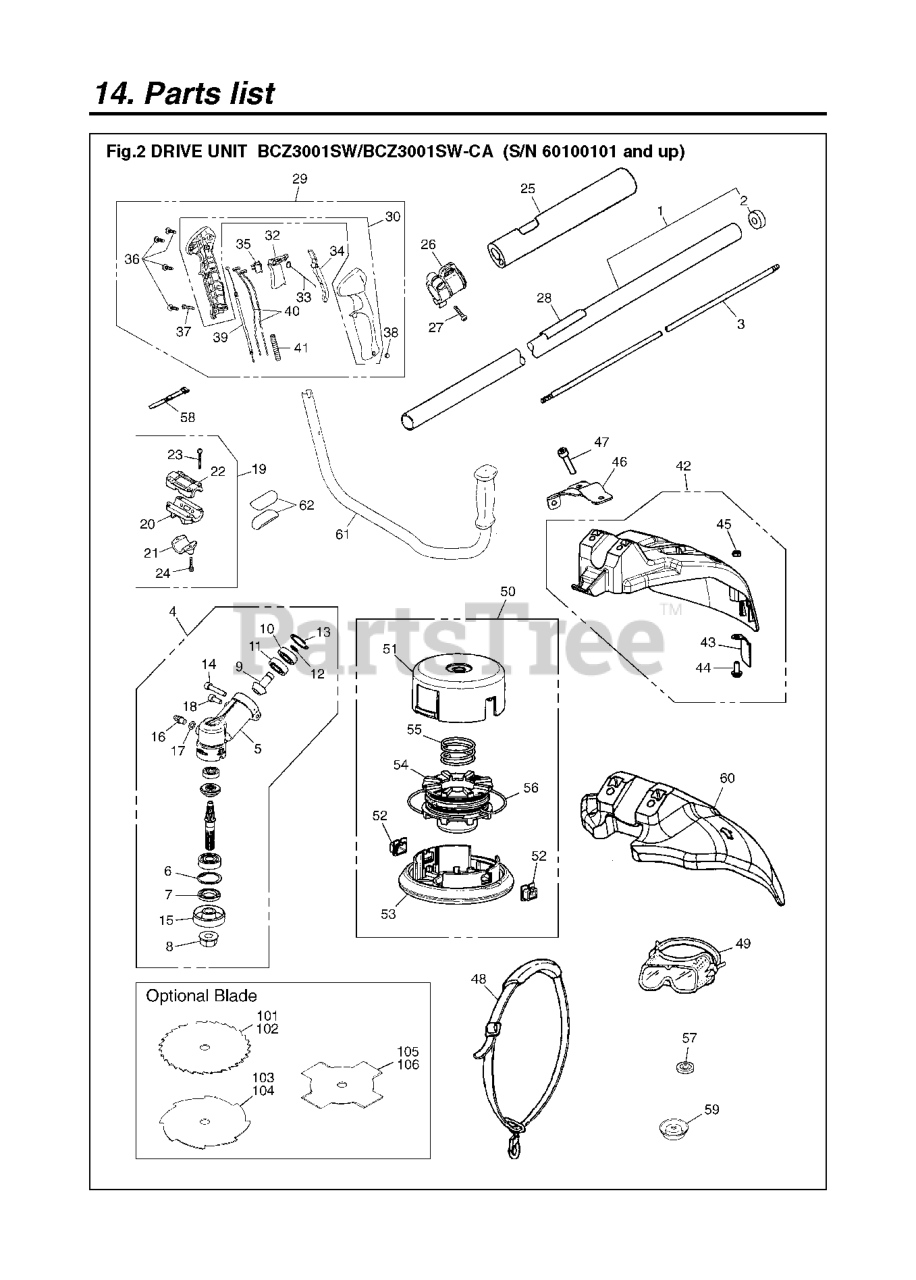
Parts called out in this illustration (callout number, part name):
1	PIPE COMP
4	RP_GEARCASE ASSY.
5	GEARCASE
6	RING,SNAP M26x1.2 RP-318013340
11	BALL BEARING
13	RP_RING
14	BOLT TORX
15	HOLDER(A)
16	FITTING
18	BOLT, TORX
19	BRACKET-ASSY***
21	CAP-L
22	BRACKET-UP
25	PROTECTOR
26	HANGER COMP.
27	SCREW
29	GRIP ASSY
30	BODY-R
42	GUARD COMP
43	BLADE (RPLS T300224120)
44	SCREW
47	BOLT, TORX
48	STRAP ASSY
49	GOGGLExxx (RPLS
50	4" TAP TRIMMER HEAD PT104
51	CASE (RPLS T318915111)***
53	COVER (RPLS T318915131)
54	HOLDER, CORD (RPLS T318915141)
57	HOLDER (B)
58	BAND(KZC)
59	COVER (10MM)
61	HANDLE COMP ***
101	Brushcutter Blade, 22 Tooth 9"
102	Brushcutter Blade, 24 Tooth 9"
103	BLADE, 8
104	Brushcutter Blade, 8 Tooth 9"
105	BLADE, 8
106	Brushcutter Blade, 4 Tooth 9"
